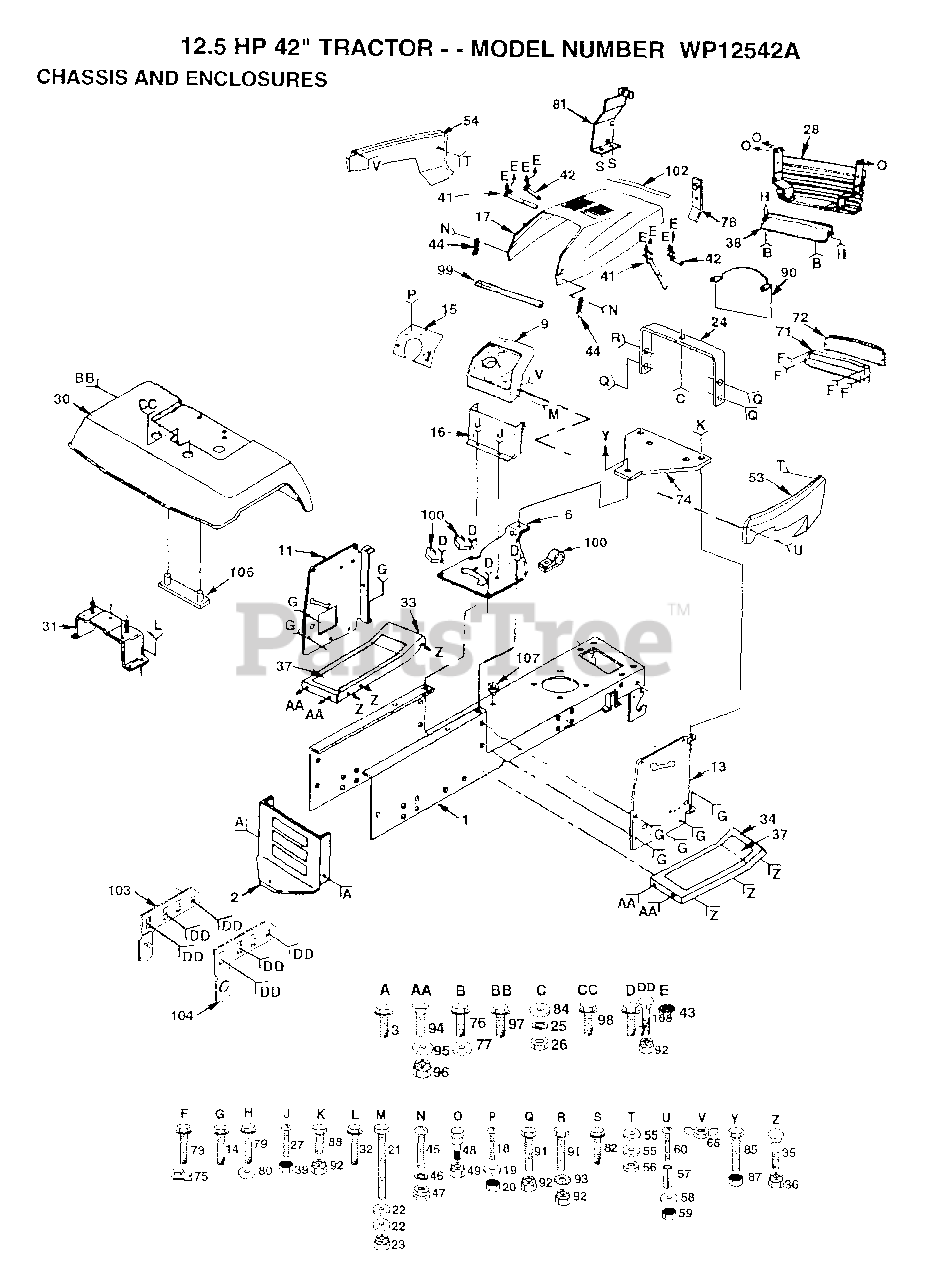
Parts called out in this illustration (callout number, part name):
3	SCREW
7	SCREW LT
11	DASH PANEL LH
13	"PANEL,DASH RH"
14	SCREW
18	SCREW
19	WASHER
22	WASHER
24	SUPPORT ASS'Y
25	LOCKWASHER
27	SCREW
32	SCREW
35	BOLT
37	FOOTREST PAD
43	NUT
44	HOOD LATCH T
45	SCREW
46	LOCKWASHER
47	WELDNUT
53	"PANEL,SIDE RH"
54	"PANEL,SIDE LH"
55	WASHER PM
57	SPACER LT
58	WASHER
60	SCREW
72	LENS LT
75	"""J"" FASTENER LT"
76	SCREW
77	WASHER
79	SCREW HEX CRT
80	WASHER
82	SCREW
84	WASHER PM
85	BOLT
90	BAFFLE HOOD VERT
93	LOCKWASHER
95	WASHER
97	SCREW LT
98	SCREW
99	FOAM-STRIP LT
100	CLIP T
103	PIVOT BRKT LH
104	PIVOT BRKT RH
105	BOLT
107	SNAP BUSHING T
